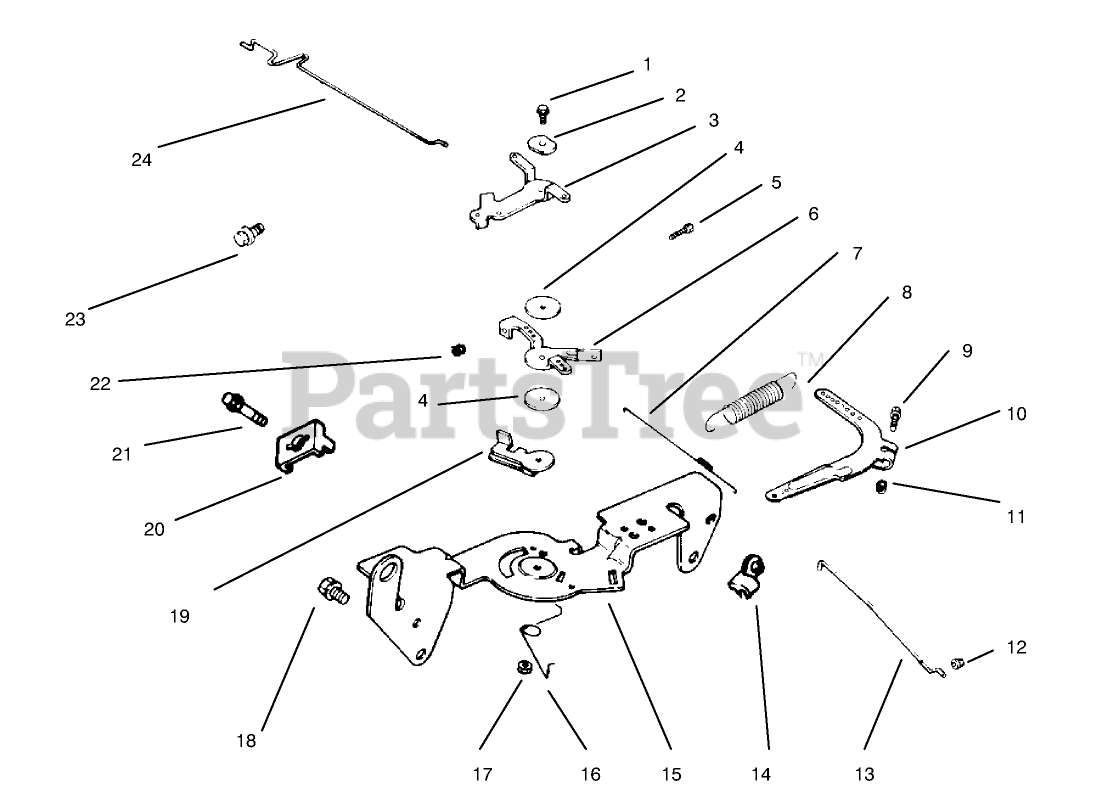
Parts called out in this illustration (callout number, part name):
2	WASHER-SPRING (1/4)
3	LEVER-CHOKE
4	WASHER-FLAT (5.5MM)
6	Lever-Control, Throttle
7	SPRING-LINKAGE
8	SPRING-GOVERNOR
10	Lever-Governor
12	BUSHING-LINKAGE, THROTTLE
13	Linkage-Throttle
14	BUSHING-RETAINING, LINKAGE
15	Bracket-Control
16	SPRING-RETURN, CHOKE
19	Lever-Actuator, Throttle
20	CLAMP-CABLE
24	Linkage-Choke
